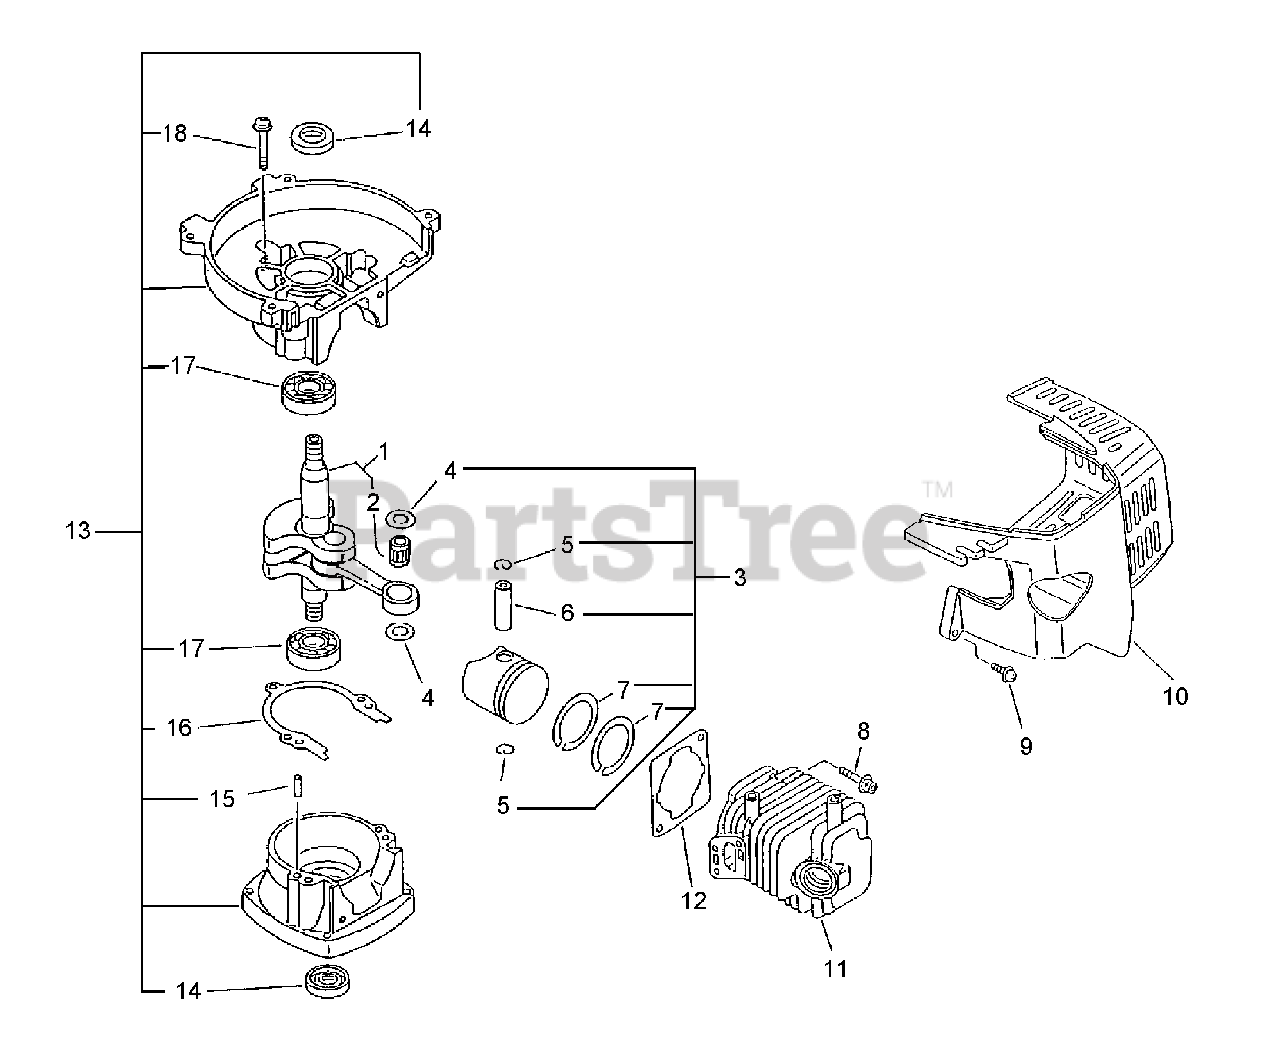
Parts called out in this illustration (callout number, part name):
1	CRANKSHAFT ASSY
2	BEARING, NEEDLE
3	PISTON KIT
4	WASHER, THRUST
5	RING, SNAP
6	PIN, PISTON 8
7	RING, PISTON
8	BOLT 5×22
9	SCREW 4×22
10	COVER, CYLINDER
11	CYLINDER
12	GASKET, CYLINDER
13	CRANKCASE SET
14	SEAL, OIL 12
15	PIN, LOCATING 4
16	GASKET, CRANKCASE
17	BEARING, BALL - 6201 C3
18	BOLT 5×28
